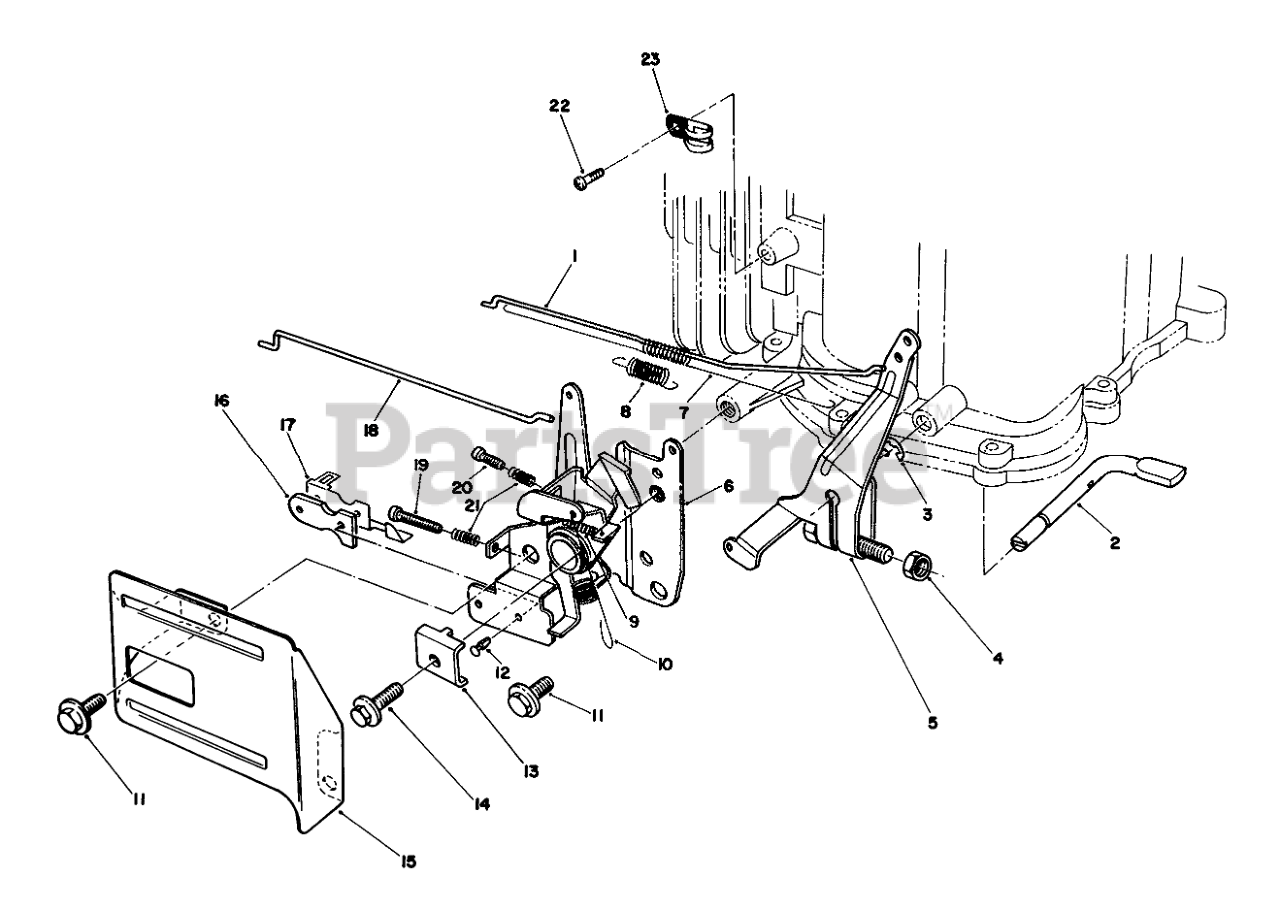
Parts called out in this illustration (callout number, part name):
1	Rod-Carburetor
2	SHAFT
3	E-RING
4	Nut
5	ARM ASM
6	THROTTLE
7	SPRING
8	SPRING
9	SPRING
10	SPRING
12	RIVET
13	CLAMP-CABLE
15	THROTTLE GUARD
16	INSULATOR-KILL SWITCH
17	TERMINAL-KILL SWITCH
18	Rod-Choke
19	SCREW
20	SCREW
21	Spring
22	SCREW
23	Clamp
